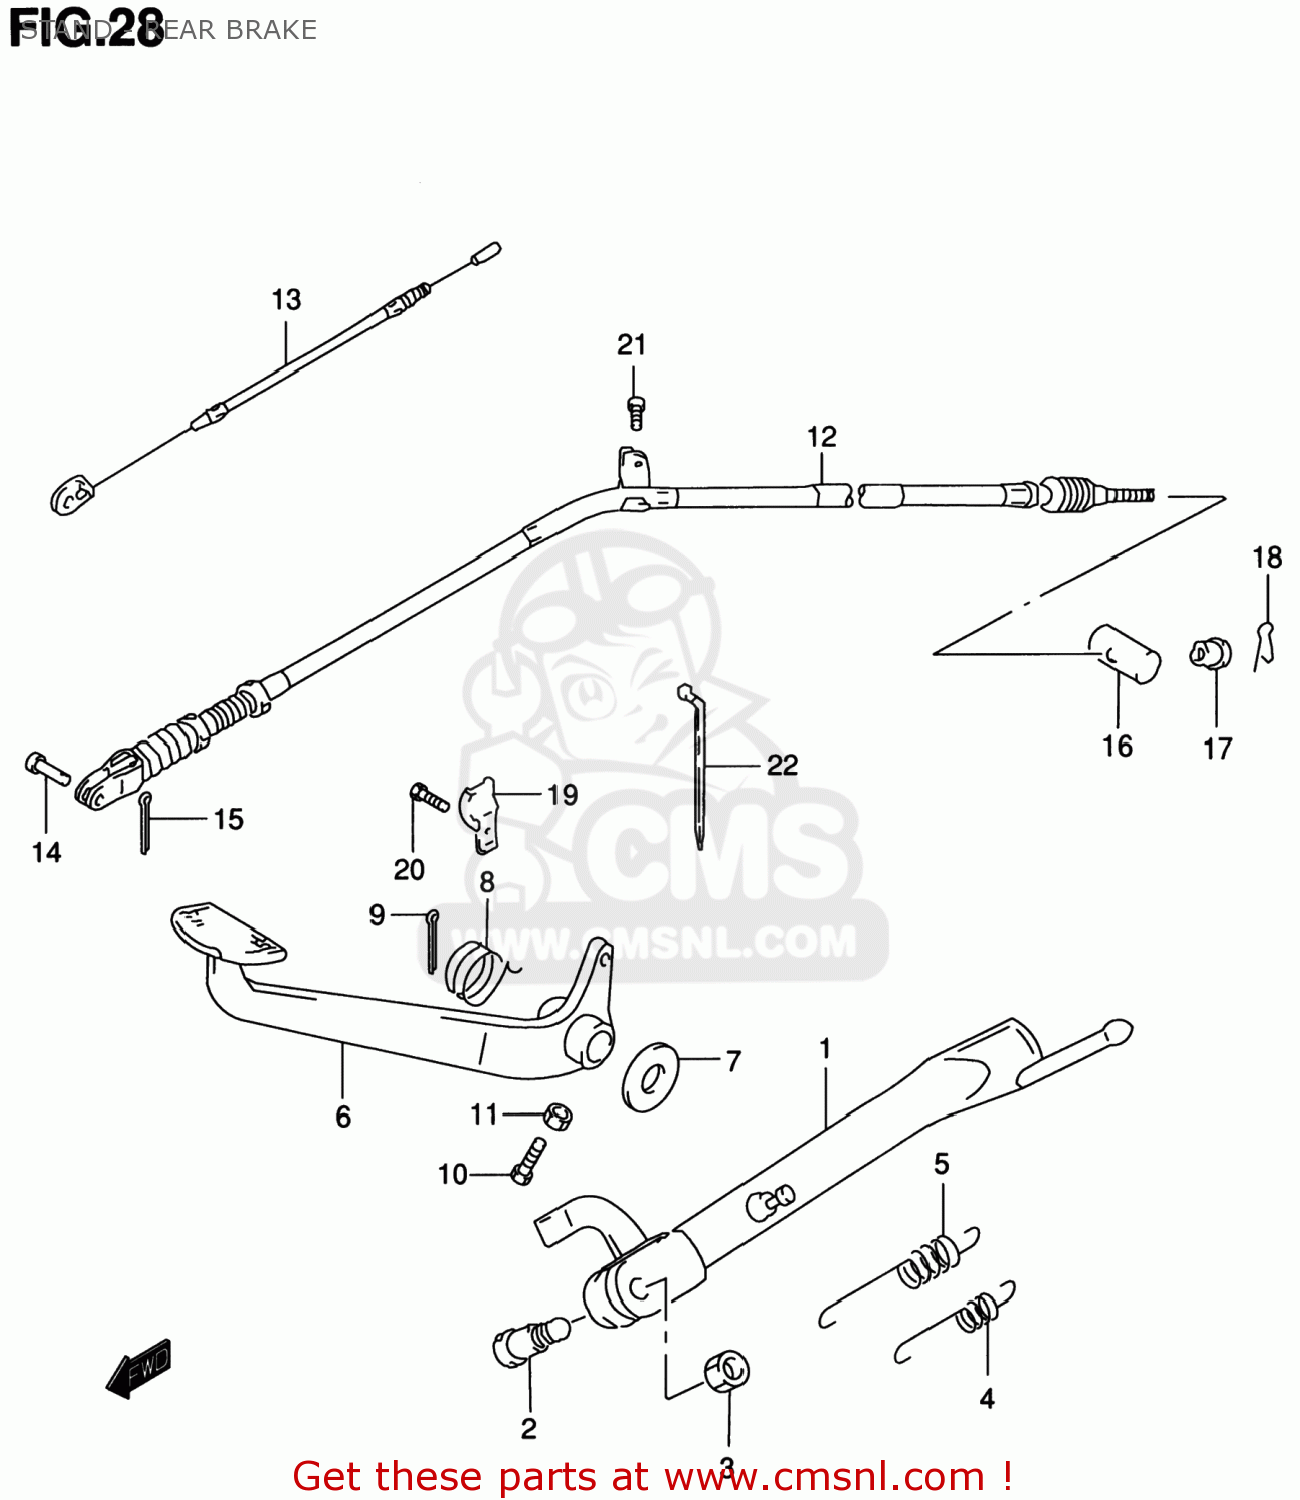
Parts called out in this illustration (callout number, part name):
1	STAND,PROP
2	BOLT(10X34)
3	NUT
4	SPRING
5	SPRING
6	PEDAL,BRAKE
7	WASHER(16.5X22X1)
8	SPRING
9	COTTER PIN
10	BOLT
11	NUT
12	CABLE,RR BRAKE
13	CABLE,STOP LAMP SWITCH
14	PIN(L:17.5)
15	PIN
16	PIN(13X18)
17	NUT
18	CLIP
19	GUIDE,RR BRAKE CABLE
20	BOLT
21	BOLT
22	CLAMP(L:145)
